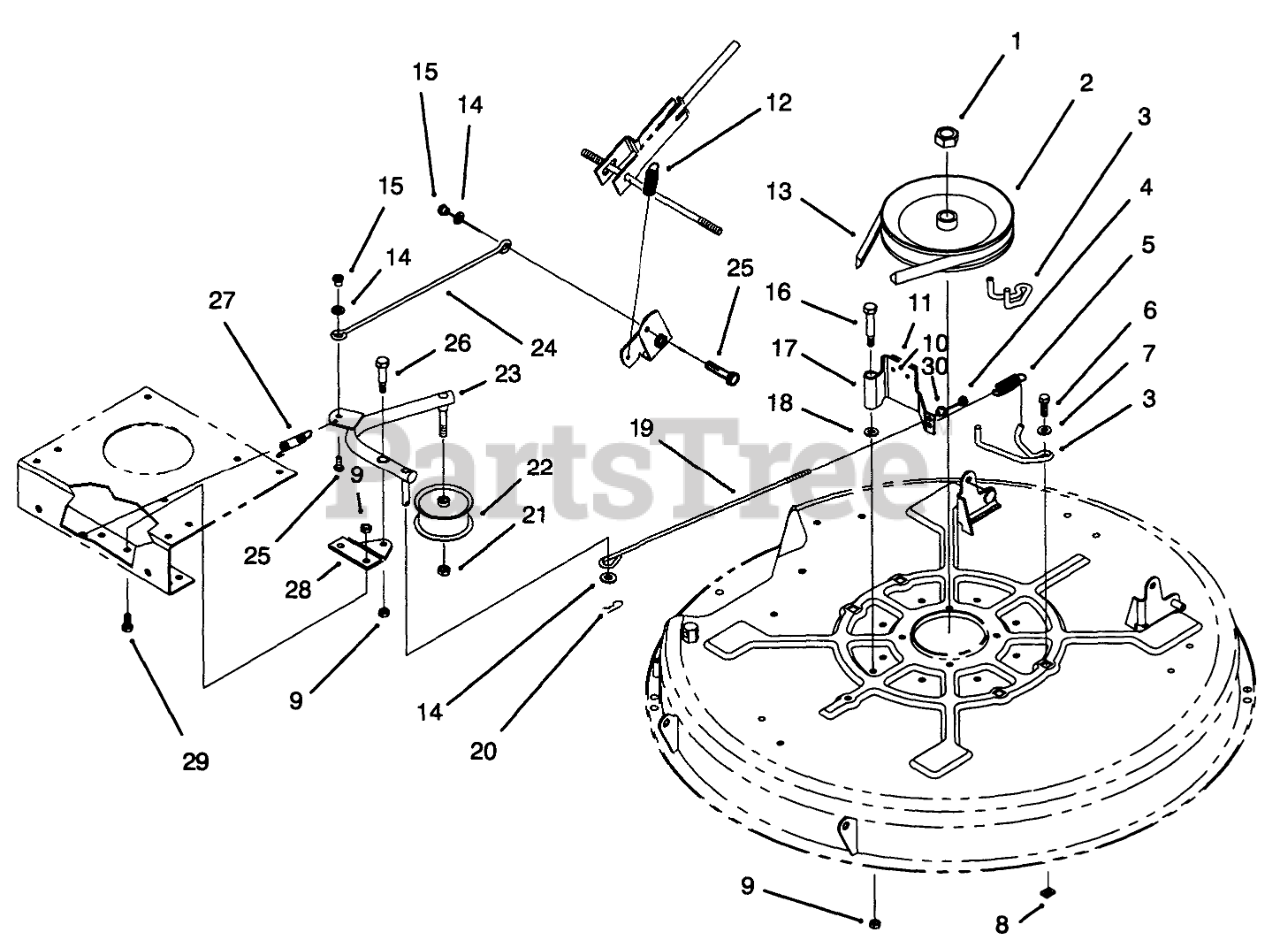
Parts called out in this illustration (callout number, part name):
1	NUT-HEX
2	PULLEY-DECK
3	GUIDE-BELT, DECK
4	NUT-LOCK, NI
5	SPRING-EXTENSION
6	SCREW-HH
7	WASHER-PIVOT
8	NUT-RETAINER
9	NUT-LOCK, NI
10	RIVET-BLIND
11	PAD-BRAKE
12	CABLE SPRING ASM
13	V-BELT
14	WASHER-FLAT
15	POST-MOUNTING, LINKAGE
16	BOLT-SHOULDER
17	Deck Brake Assembly (Incl. Ref. #10 & 11)
18	WASHER-PLAIN
19	ROD-BRAKE, DECK
20	PIN-COTTER
21	NUT-LOCK, NI
22	PULLEY-IDLER
23	Arm-Idler
24	ROD-ENGAGE, DECK
25	SCREW-HHF
26	SCREW-SHOULDER, HH
27	SPRING-RETURN, BRAKE
28	Plate-Idler Mount
29	SCREW-HH
30	BALL-SWIVEL, STOP
